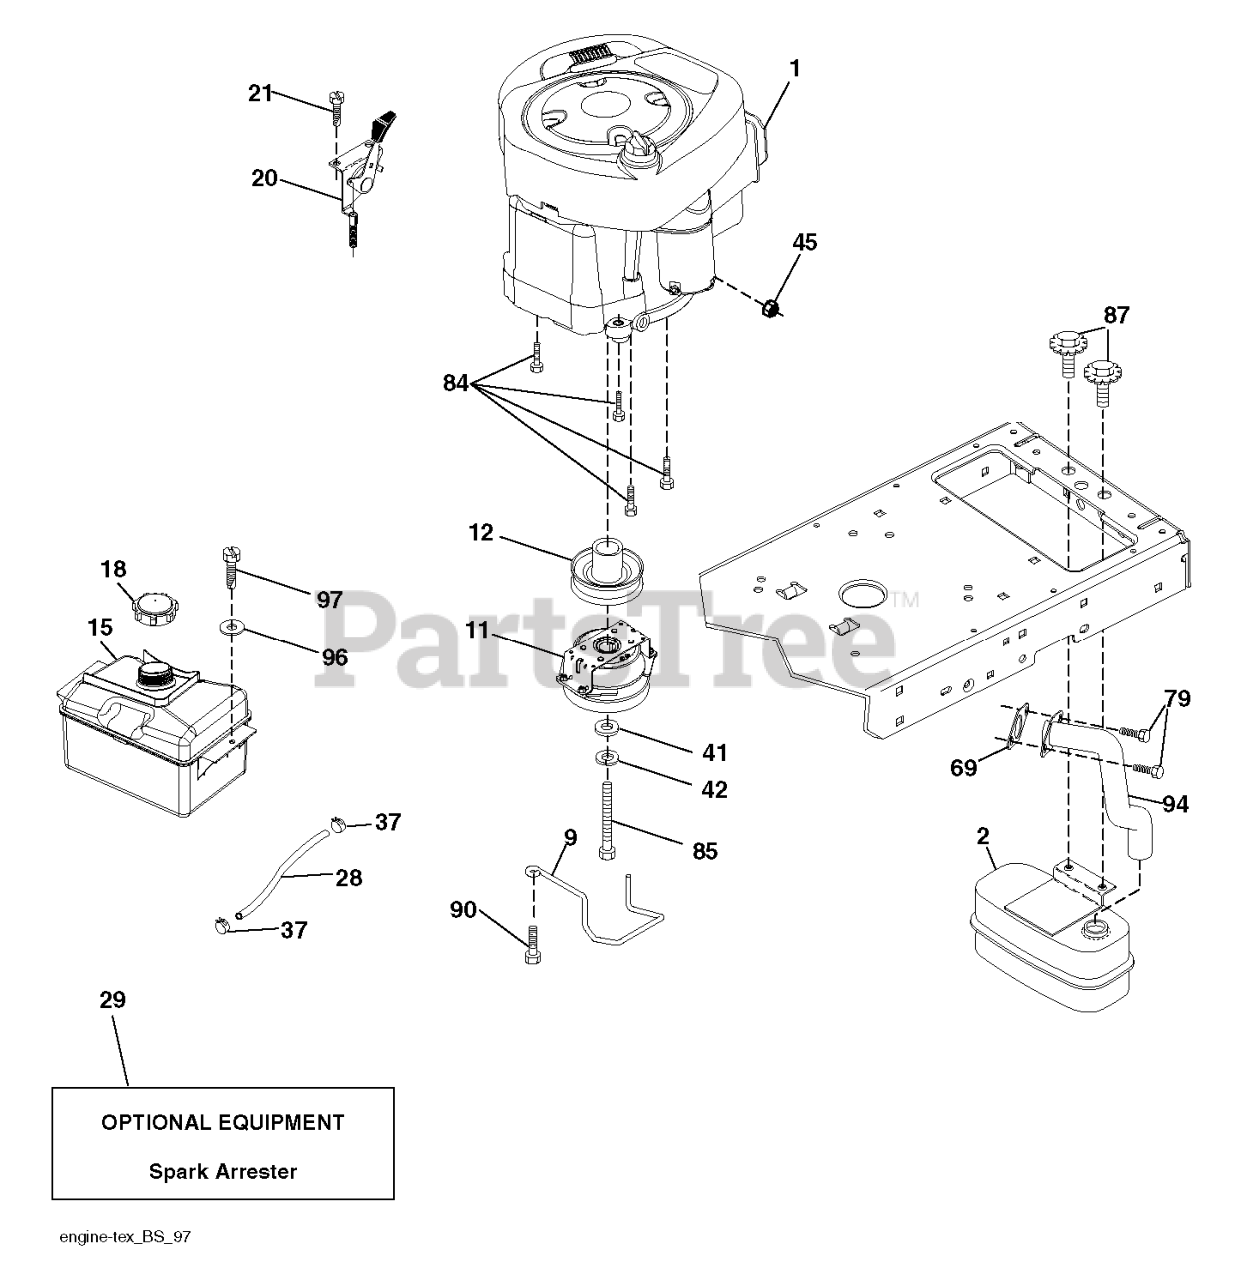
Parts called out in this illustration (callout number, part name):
2	MUFFLER.SINGLE.LRG.BRIGGS.KOHL
9	KEEPER BELT ENGINE
11	CLUTCH.ELECTRIC.LT.48"*
12	PULLEY.ENGINE.TUFFTORQ
15	FUEL.TANK.ASM.NON-EPA
18	CAP ASM.FUEL.2.25"FR.
20	CONTROL.TH/CK.C.
21	SCREW.#10 X 0.750.BOS
28	LINE.FUEL.20
29	KIT.SPARK ARRESTOR 794945 B&S
37	HOSE CLAMP
42	LOCKWASHER
45	NUT
69	REPL BY 532 27 22-93
79	SCREW.SOCKET HD.5/16-1
84	SCREW.3/8-16
85	BOLT HEX 7/16-20X4-1/4"
87	BOLT.5/16-18UNCX3/4 W/SEMS.BLK
90	SCREW 3/8-16X1
94	RP.EXHAUST.TUBE.B&S.28/31
96	WASHER
97	SCREW HEXWSHR 1/4-20X3/4
